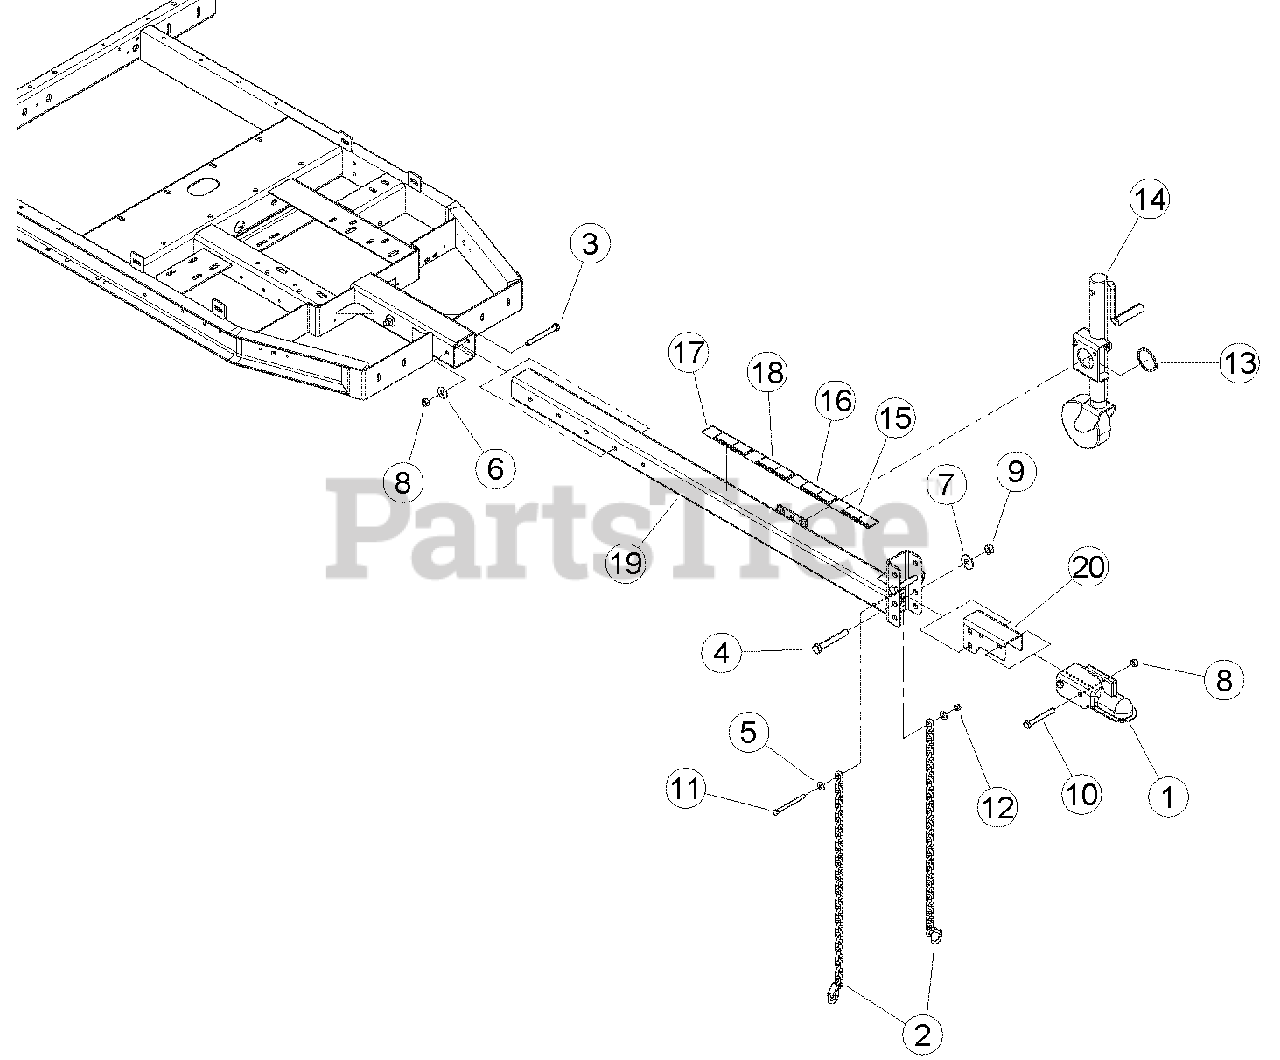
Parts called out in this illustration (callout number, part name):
1	COUPLER, 2 IN
2	CHAIN, SAFETY, 5000 LB W/LATCH
3	BOLT, 1/2 X 4-1/2 HEX HD GR5
4	BOLT, 5/8 X 4-1/2 HEX HD GR5
5	WASHER, 3/8 FLAT ZP
6	WASHER, 1/2 FLAT ZP
7	WASHER, 5/8 FLAT ZP
8	NUT, 1/2 CENTERLOCK GRB ZP
9	NUT, 5/8 CENTERLOCK
10	BOLT, 1/2 X 4 HEX GR5 ZP
11	BOLT, 3/8 NC X 4-1/2 HEX HD
12	NUT, 3/8 NYLOCK
13	SNAP RING, 2-1/2 EXTERNAL
14	JACK, PIVOTING W/SWIVEL CASTOR
15	DECAL, SAFETY CHAINS
16	DECAL, TRAILER ELECTRICAL
17	DECAL, CHECK WHEELS
18	DECAL, SAFE COUPLING
19	WELDMENT, HITCH POLE W/PLATE
20	MOUNT, COUPLER
